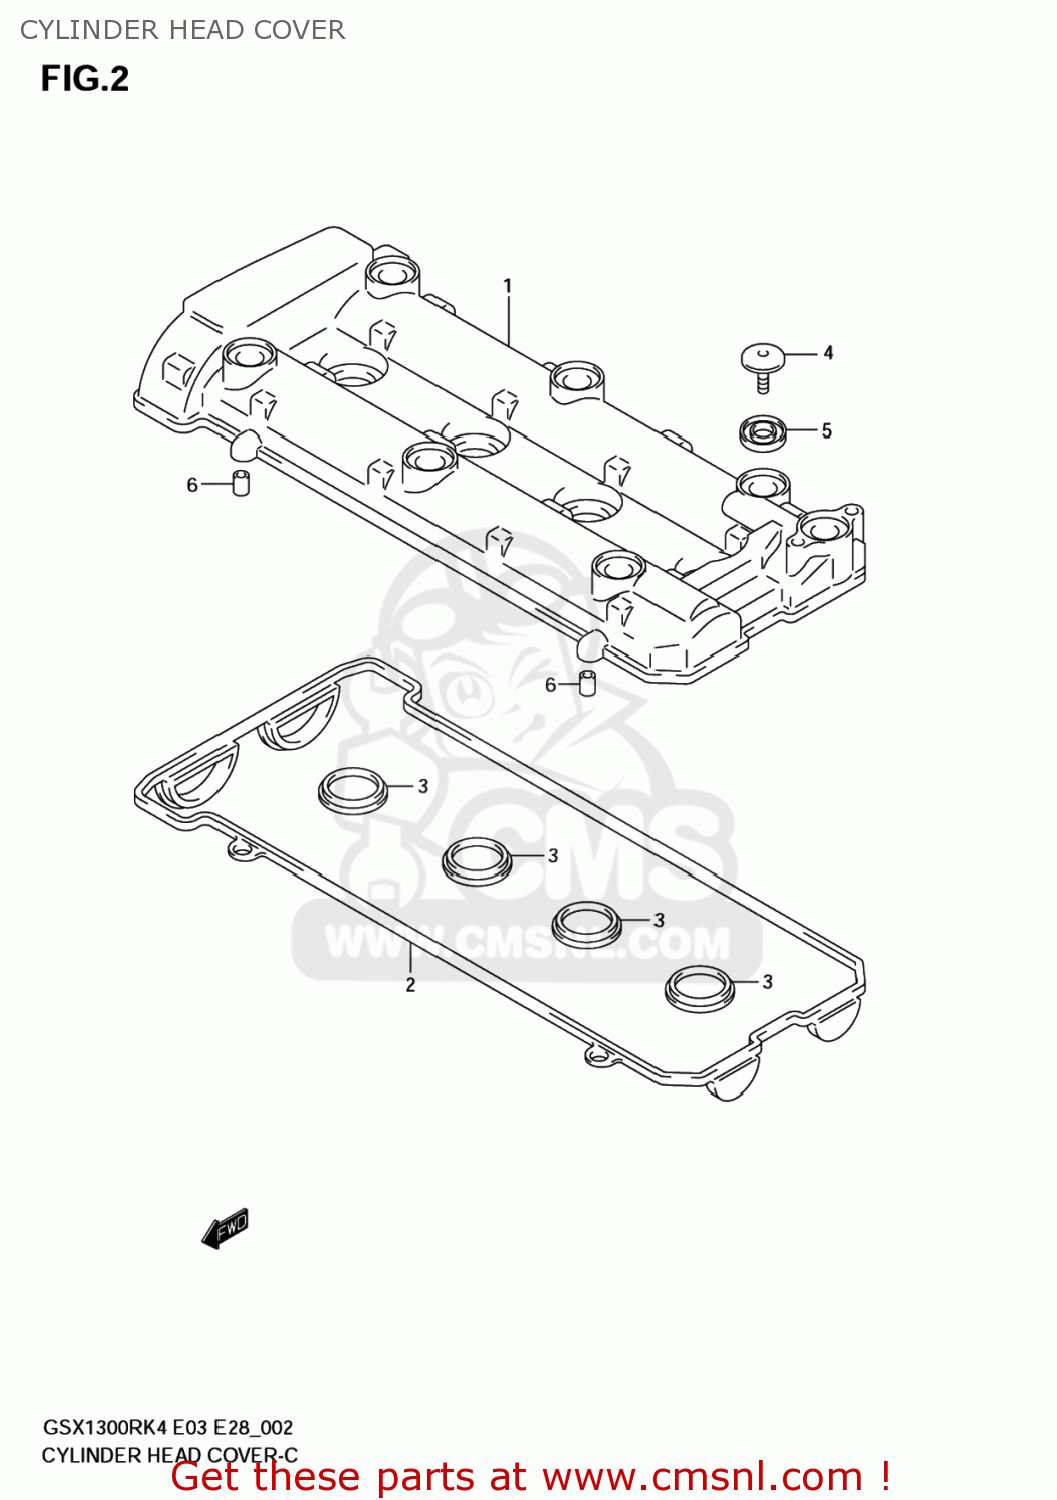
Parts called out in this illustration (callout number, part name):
1	COVER,CYLINDER HEAD
2	GASKET,CYL HEAD COVER NO.1 (NAS)
3	GASKET,CYL HEAD COVER NO.2
4	BOLT(7X17.5)
5	WASHER(10.6X25.5X2.3)
6	PIN
